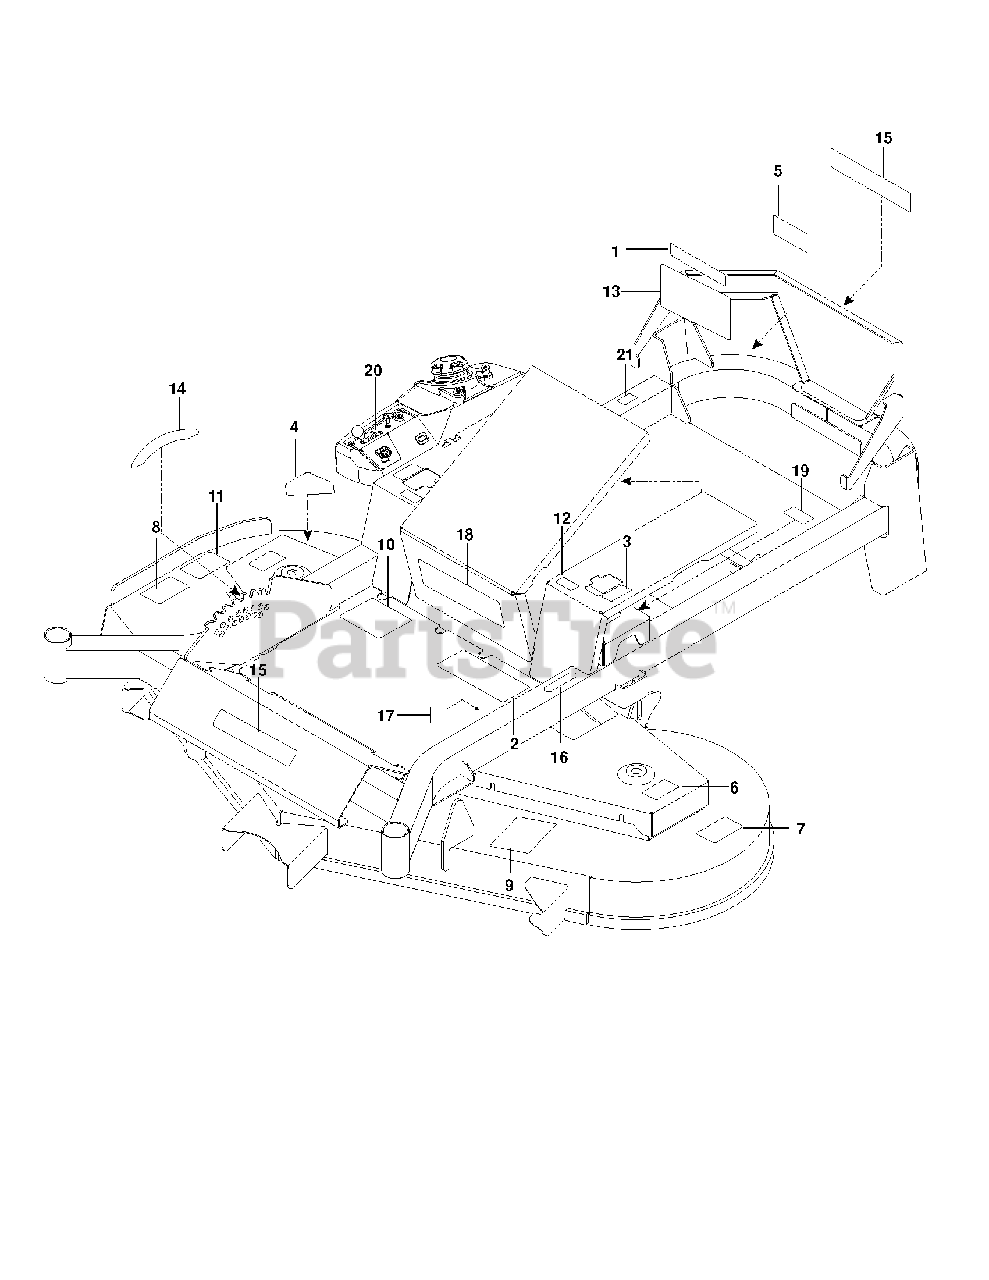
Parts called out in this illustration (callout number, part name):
2	DECAL, WARNING
3	DECAL, MOTION CONTROL
4	DECAL, CPSC
5	DECAL, BELT DRIVE
8	DECAL, EURO SEVERING
9	DECAL, BELT ROUTING
10	DECAL, WARNING
12	DECAL, TRACKING
13	DECAL, SERVICE
14	DECAL, HEIGHT 5"
16	DECAL, PARK BRAKE
19	DECAL, FUEL
21	DECAL, ECM, AUSTRALIA
